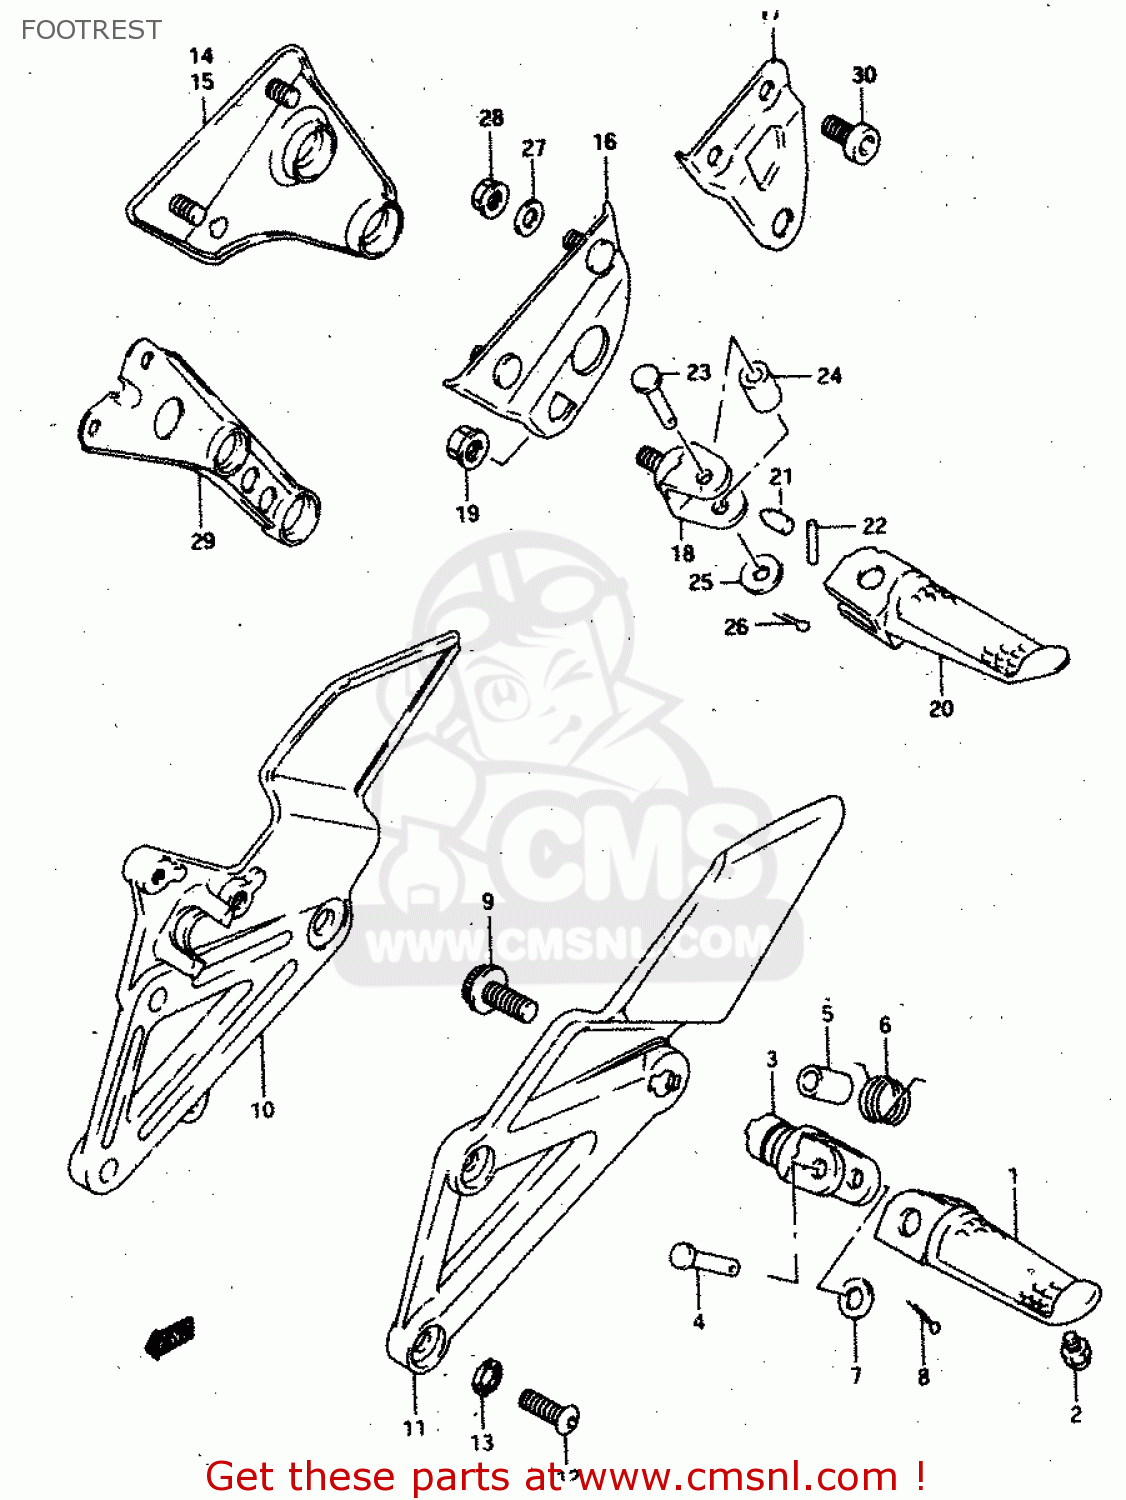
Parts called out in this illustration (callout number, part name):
1	BAR,FR FOOTREST,R
2	BOLT(6X6)
3	HOLDER,FOOTREST
4	PIN
5	SPACER(8.1X12X22)
6	SPRING
7	WASHER
8	PIN 20X15
9	BOLT
10	BRACKET,FR FOOTREST,R
11	BRACKET,FR FTR
12	BOLT(8X20)
13	WASHER
14	FOOTREST ASSY, PILLION RH
15	FOOTREST,PILL.ION
16	FOOTREST ASSY, PILLION LH
17	FOOTREST ASSY,PILLION,L
18	HOLDER,PILLION FOOTREST
19	NUT 10MM
20	BAR,PILLION FOOTREST R
21	CUSHION,FOOTREST HOLDER
22	ROLLER,FOOTREST HOLDER
23	PIN
24	SPACER(8.1X12X22)
25	WASHER
26	PIN 20X15
27	WASHER
28	NUT
29	BRACKET,MUFFLER 2ND
30	BOLT
